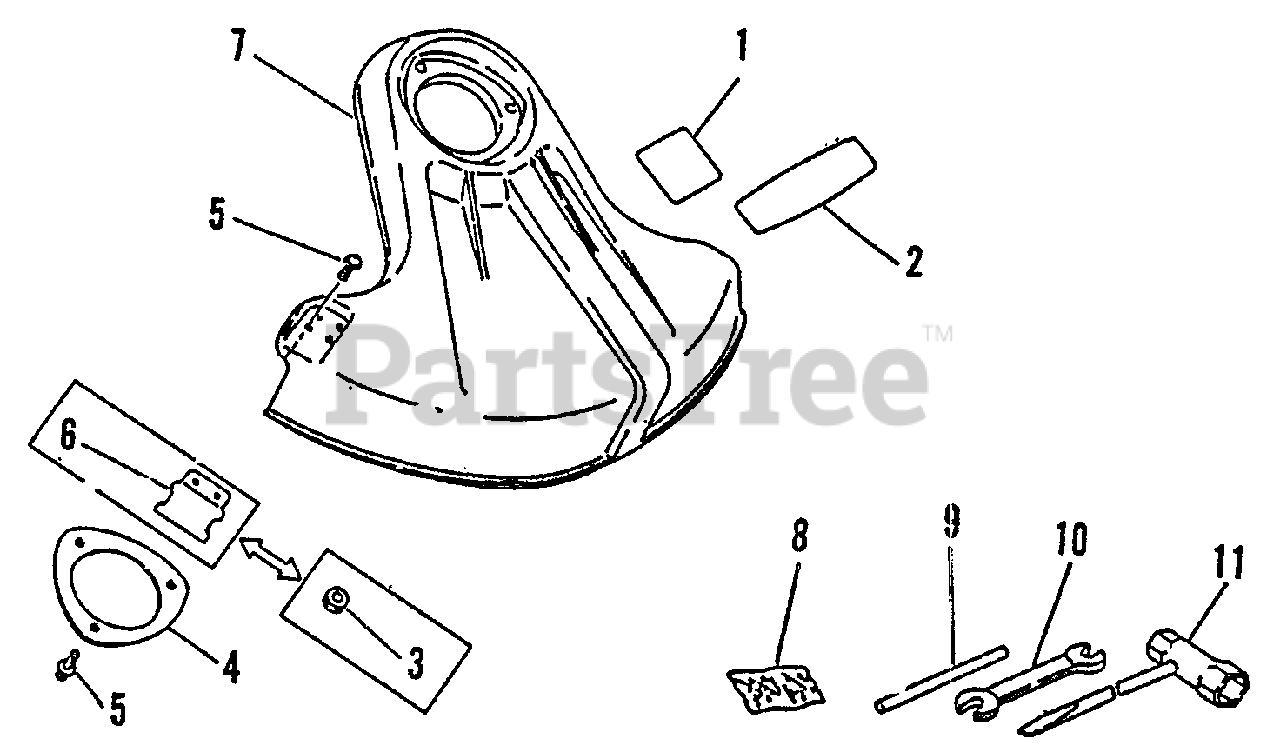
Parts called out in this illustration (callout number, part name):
1	LABEL - CAUTION
2	LABEL - LESCO
4	PLATE, SHIELD
5	SCREW - 5X16
6	KNIFE, TRIMMER LINE
7	SHIELD, DEBRIS - PLASTIC
8	PIN, SPLIT - 2X22
9	LOCKING TOOL
10	SPANNER - 8X10mm
11	T-WRENCH - 17X19mm
